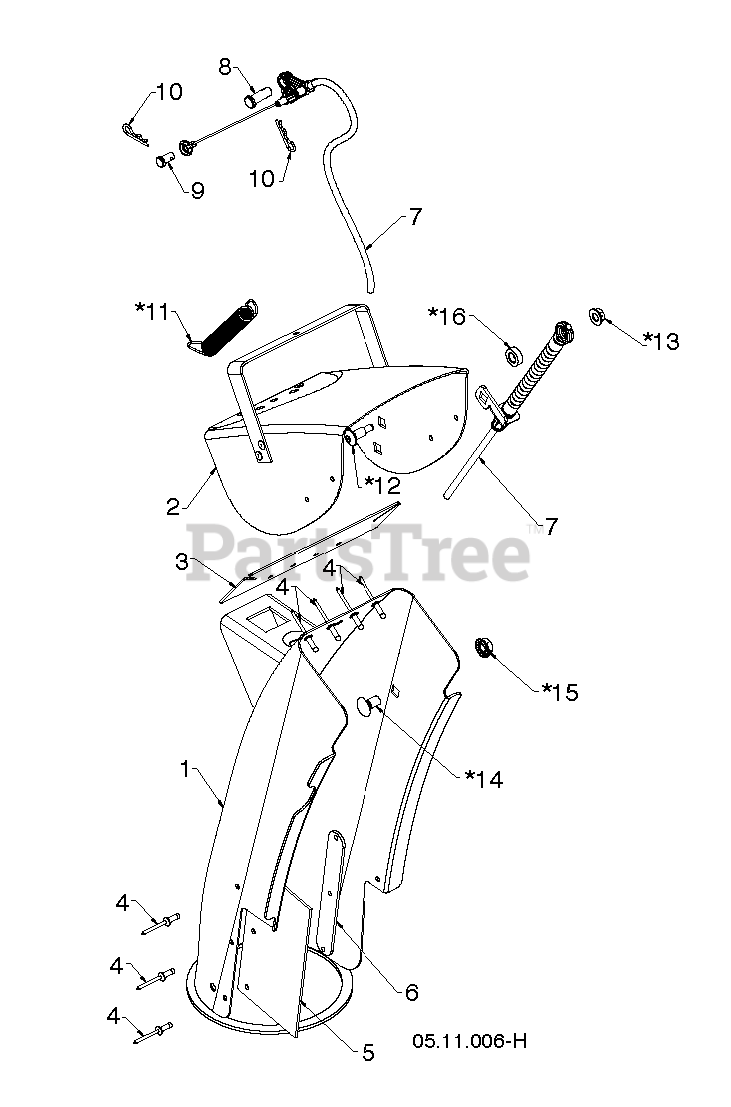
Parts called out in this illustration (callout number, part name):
1	ASM.CHUTE/DEFLECTOR.668
7	CABLE CONTROL.CHUTE.DEFLECTOR.
8	PIN CLEVIS 5/16X.875
9	PIN CLEVIS .25 X .31
10	HAIRPIN.SOFT.ZINC.059X1.125
